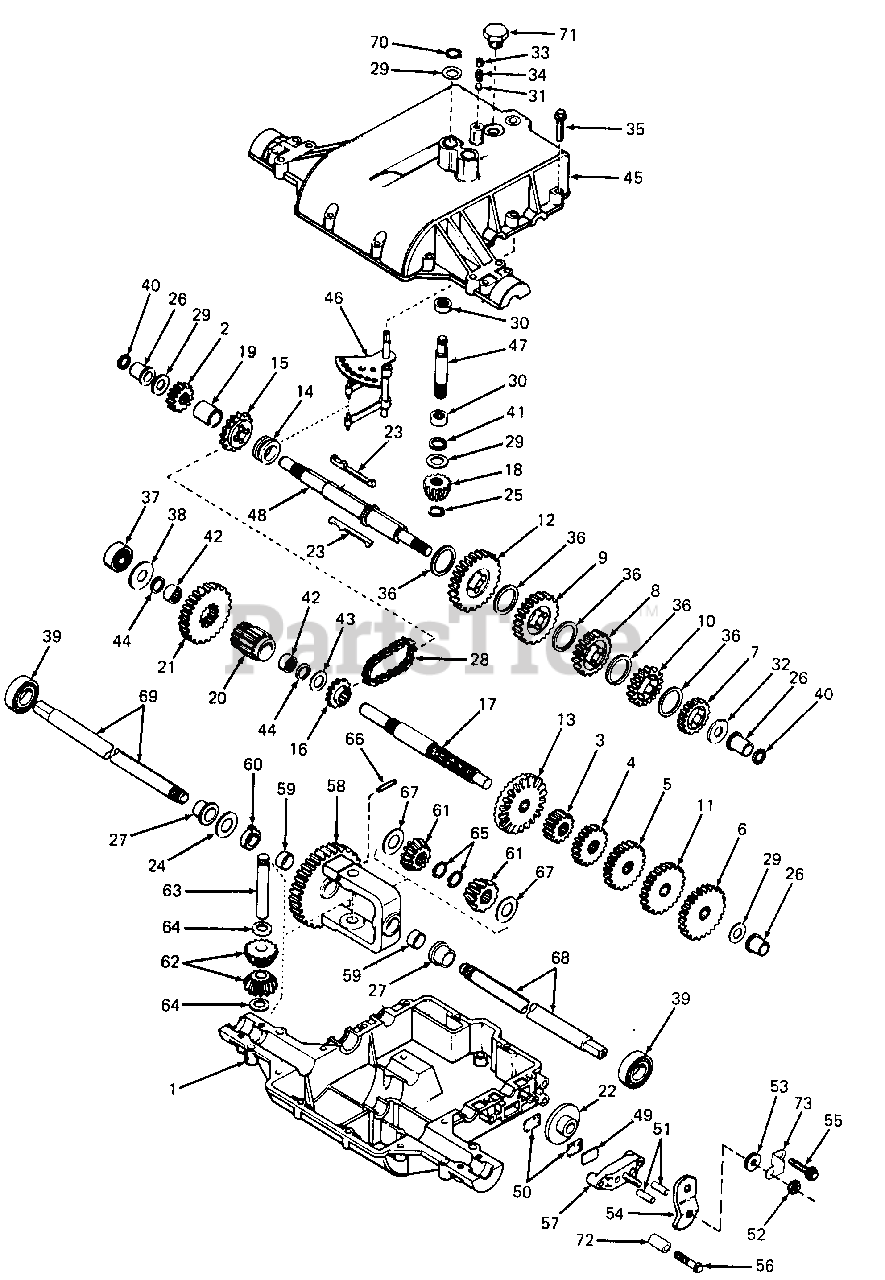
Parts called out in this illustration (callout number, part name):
1	Case, Transaxle
2	Gear, Spur (15 teeth)
3	Gear, Spur (12 teeth)
4	Gear, Spur (20 teeth)
5	Gear, Spur (25 teeth)
6	Gear, Spur (30 teeth)
7	Gear, Spur (20 teeth)
8	Gear, Spur (25 teeth)
9	Gear, Spur (30 teeth)
10	Gear, Spur (22 teeth)
11	Gear, Spur (28 teeth)
12	Gear, Spur (37 teeth)
13	Gear, Bevel (42 teeth)
14	Collar, Shift
15	Sprocket (18 teeth)
16	Sprocket (9 teeth)
17	Shaft, Counter
18	Bevel Pinion, Input
20	Pinion, Output
21	Gear, Output
22	Disk, Brake
23	Key
25	Ring, Retaining
26	Bushing, Flanged
27	Bushing, Flanged
28	Chain, Roller
29	Washer, Thrust
30	Bearing, Needle
31	Ball, Steel
32	Washer, Thrust
33	Screw, Set, 3/8-16 X 3/8
35	Screw, Hex-Hd Thread Forming 1/4-20 X 1-1/4
36	Washer, Thrust
37	Bearing, Ball
38	Washer, Flat
39	Bearing, Ball
40	Ring, Square Cut
41	Ring, Square Cut
42	Bearing, Needle
43	Washer, Flat
44	Ring, Square Cut
45	Cover, Transaxle
46	Rod & Fork Assy, Shift
47	Shaft, Input
48	Shaft, Brake
49	Plate, Brake Pad
50	Pad, Brake
51	Pin, Dowel
52	Locknut, 5/16-24
53	Washer, Flat
54	Lever, Brake
55	Screw, Hex-Hd Thread Forming 1/4-20 X 1-1/4
56	Screw, Hex-Hd Thread Forming, 1/4-20 X 2-1/4
57	Holder, Brake Pad
58	Gear Assy, Differential
61	Gear, Bevel
62	Pinion, Bevel
63	Pin, Drive
64	Washer, Thrust
65	Ring, Retaining
67	Washer, Thrust
68	Axle,15-1/4 Long - RH
69	Axle, 13-3/8 Long - LH
70	Ring, Retaining
71	Plug, Hex-Hd, 9/16-18 Thread
73	Bracket, Brake Lever
